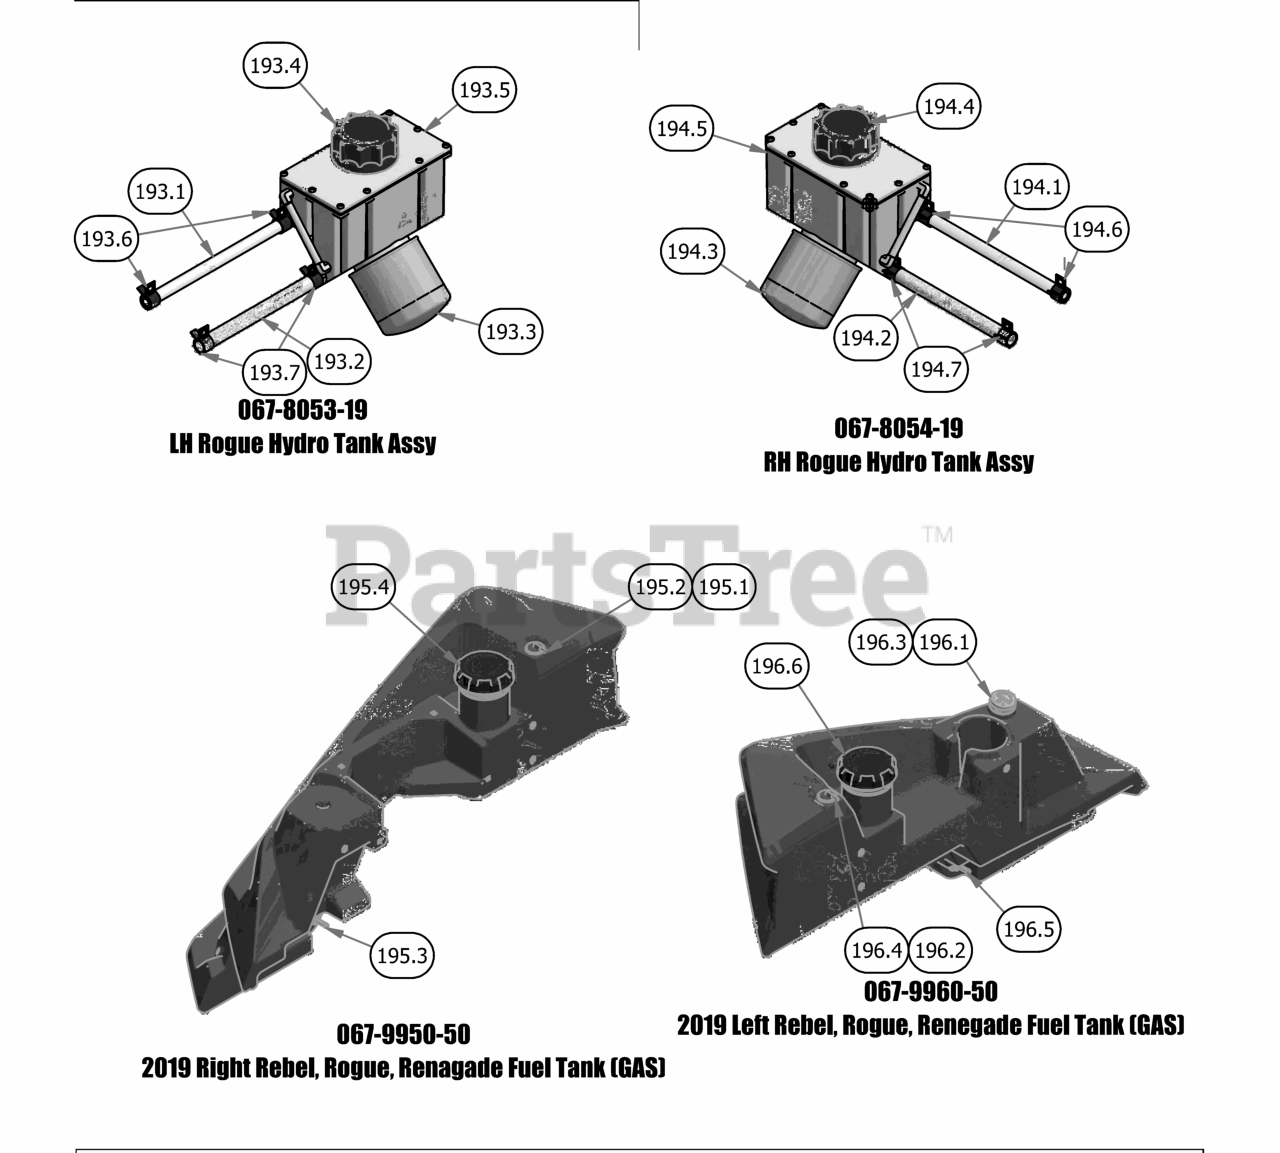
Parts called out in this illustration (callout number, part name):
193.1	3/8" Clear Hose x 4 1/2"
193.2	1/2 Clear Braded Hose Priced/Foot x 9.5"
193.3	Hydraulic Filter
193.4	Hydraulic Tank Cap W/Dipstick
193.5	2019 Left Outlaw Gen2 Hydro Tank Suspension Only
193.6	3/8" Hose Clamp
193.7	1/2 Hose Clamp
194.1	3/8" Clear Hose x 4 1/2"
194.2	1/2 Clear Braded Hose Priced/Foot x 9.5"
194.3	Hydraulic Filter
194.4	Hydraulic Tank Cap W/Dipstick
194.5	2019 Right Outlaw Gen2 Hydro Tank Suspension Only
194.6	3/8" Hose Clamp
194.7	1/2 Hose Clamp
195.1	Roll Over Valve Grommet
195.2	Rollover Valve
195.3	Fuel Pick-up
196.1	Fuel Gauge with Grommet
196.2	Roll Over Valve Grommet
196.3	Fuel Gauge Grommet
196.4	Rollover Valve
196.5	Fuel Pick-up
